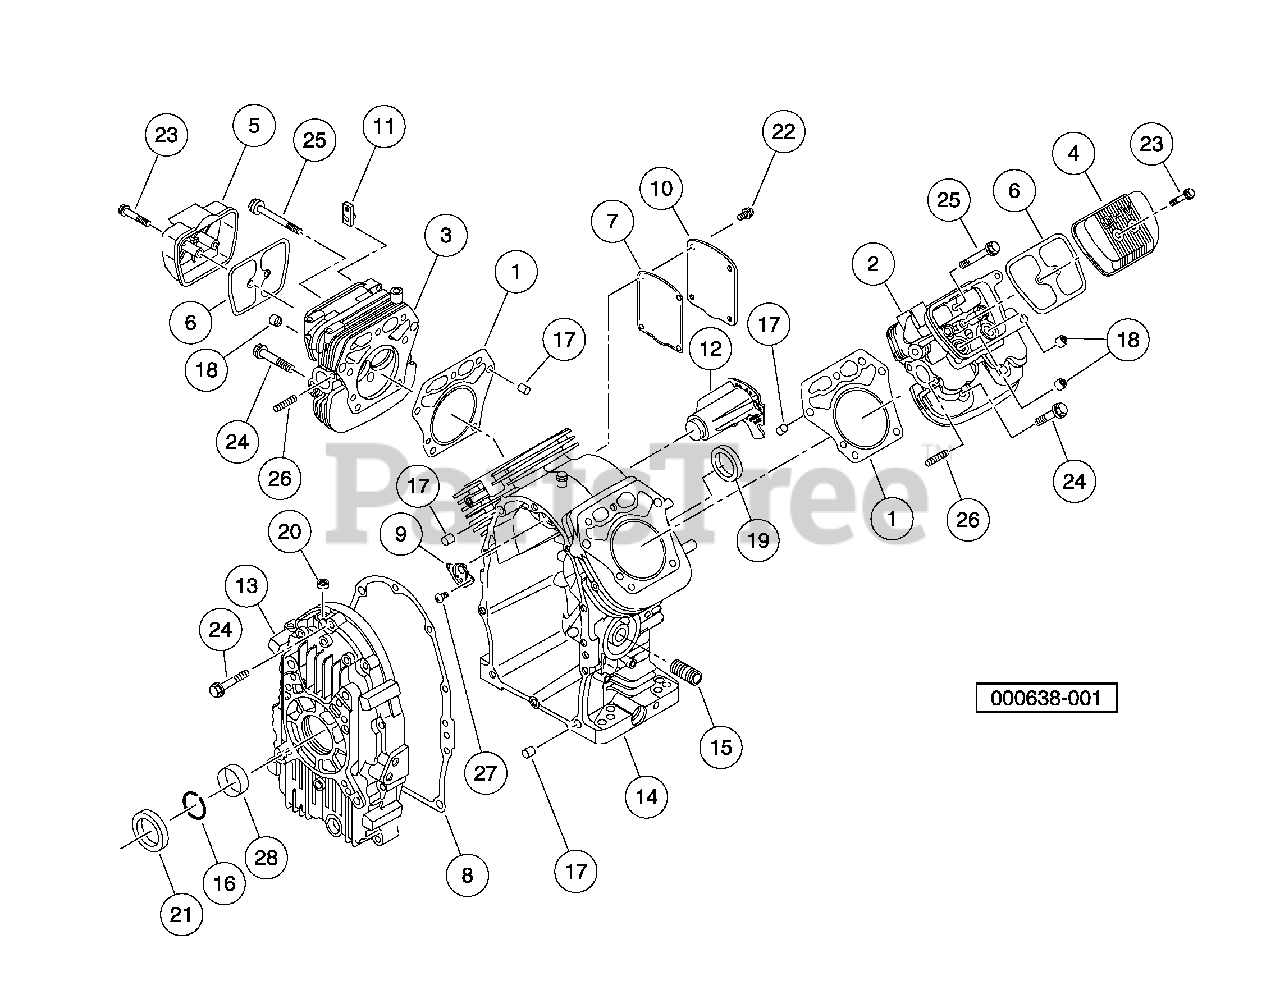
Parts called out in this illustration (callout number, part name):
1	Gasket, Head, Cyl, Fh
2	Head, Cyld 1, Fh
3	Head, Cyld 2, Fh
4	Cover, Rocker, Cyld 1, Fh
5	Cover, Rocker, Cyld 2, Fh
6	Gasket, Rocker, Cover, FH
7	Gasket, Breather, Fh
8	Gasket, Cover, Crank, Fh
9	Valve, Assy, Reed, Fh
10	Cover, Crkcase, Comp, Fh
11	Pipe, Head, Comp, Clyd, Fh
12	Pipe, Crkcase, Comp, Fh
13	Cover, Crankcase, Fh
14	Crankcase, Comp, Fh
15	Nipple, Oil Filter, Fh
16	Ring, Snap, Fh
17	Pin, Head, Fh.
18	Seal, Oil, Valve, Fh
19	Seal, Oil, Crank, Rear, Fh
20	Seal, Oil, Governor, Fh
21	Seal, Oil, Crank, Front, Fh
22	Bolt, Flg, M6 X 1.0 X 12
23	Bolt, Flg, M6 X 1.0 X 40
24	Bolt, Flg, M8 X 1.25 X 50
25	Bolt, Flg, M8 X 1.25 X 75
26	Stud, M8 X 1.25, Exhaust, Fh
27	Screw, Pan, Governor, Fh
28	Bushing, Main, Fh
